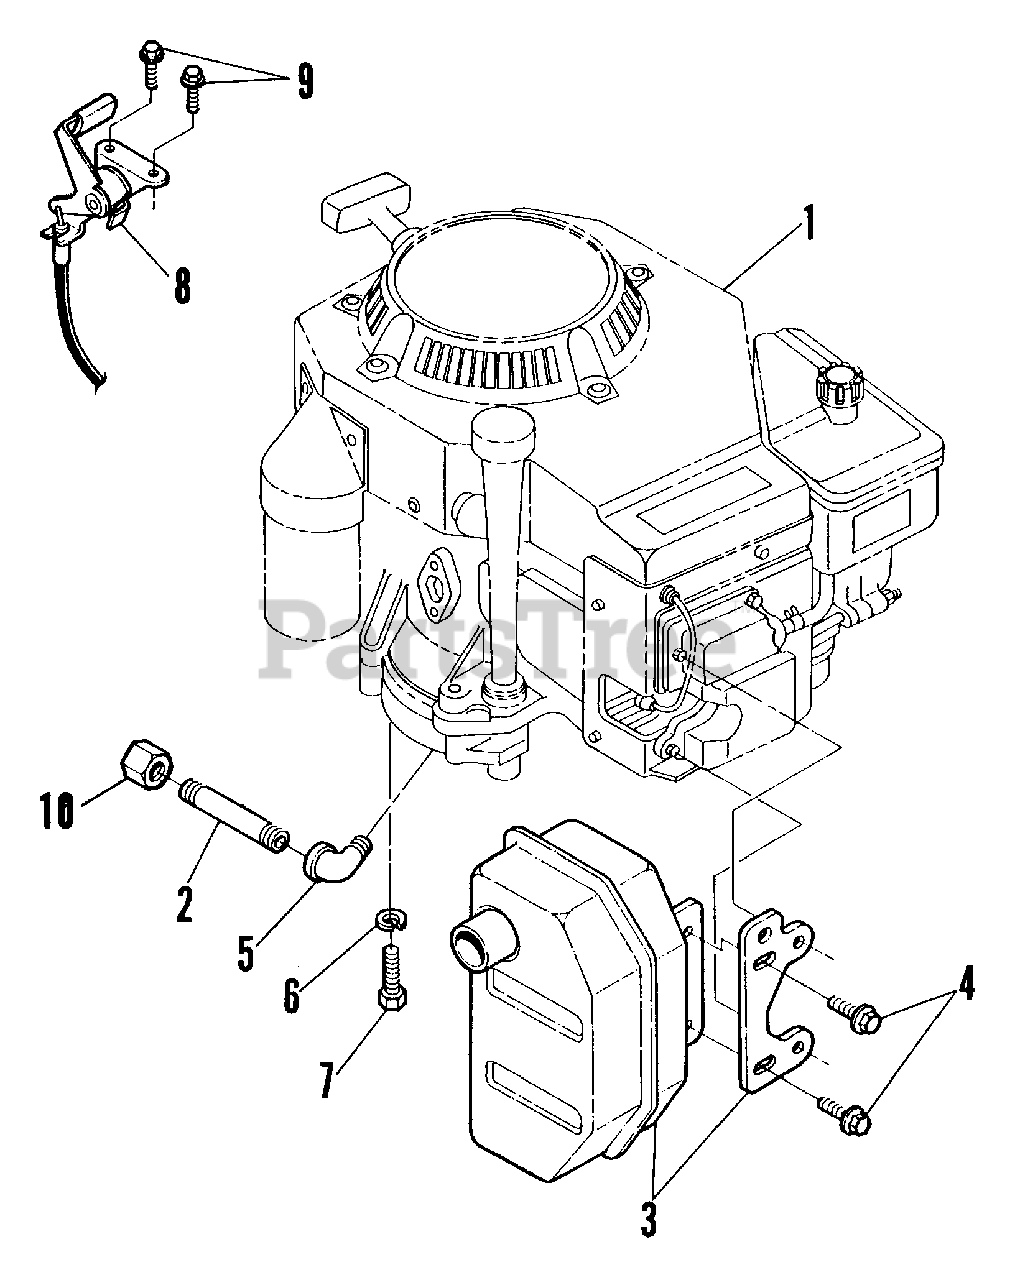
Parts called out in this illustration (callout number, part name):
1	ENGINE, 14 HP Kohler
2	PIPE, Oil Drain
3	MUFFLER GROUP, 14 H.P.Kohler
4	SCREW, M6 x 16mm Hex Cap
5	ELBOW, 3/8" Street 90°.
6	WASHER, 5/16" Lock
7	BOLT, M8 1.25 x .25, Tap, Gr. 5
8	CONTROL, Throttle
9	SCREW, #10-24 x 1/2" Hex Washer Self-Tap (Torx)
10	CAP, Oil Drain
